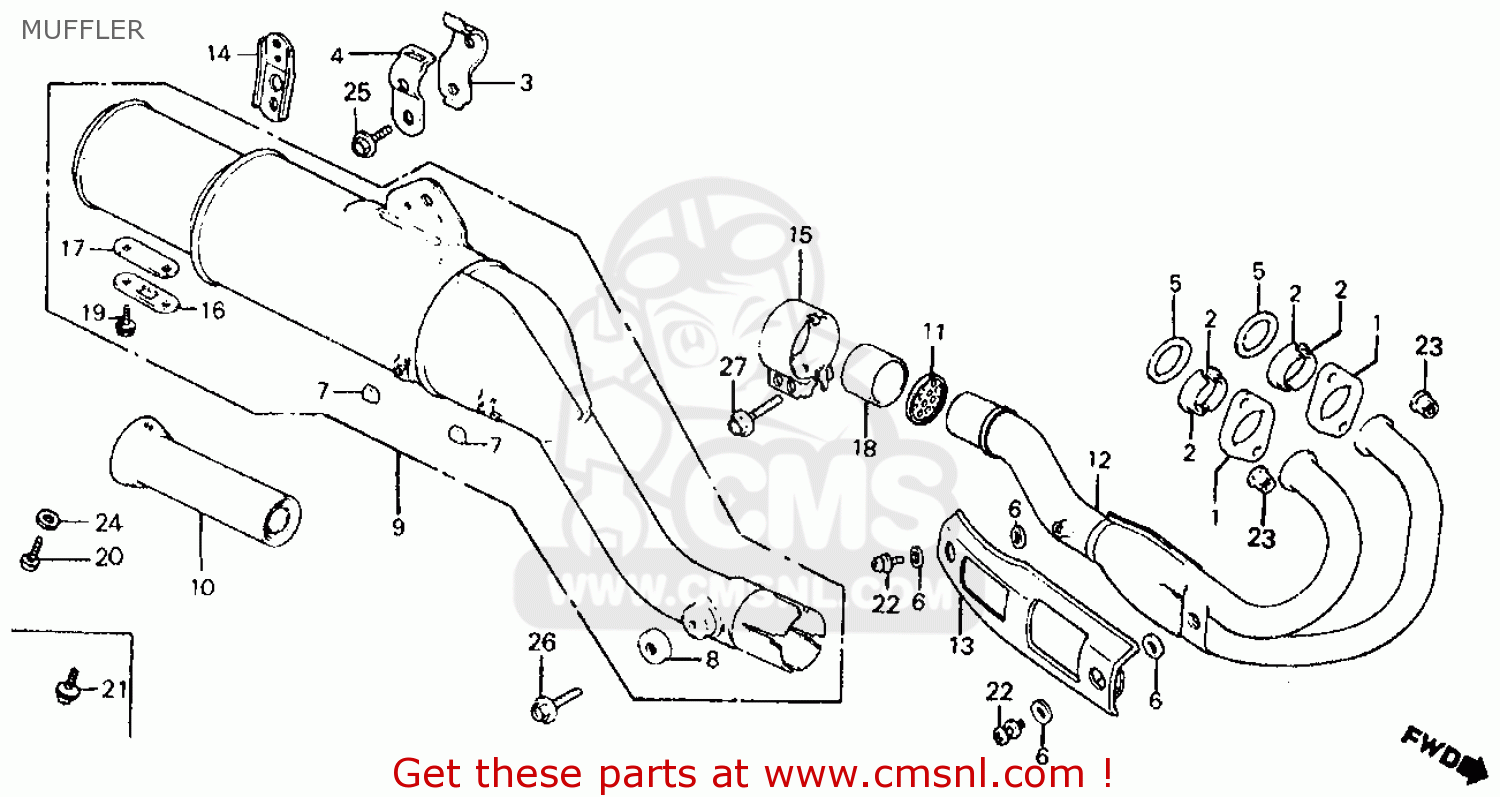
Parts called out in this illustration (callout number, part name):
1	JOINT,EX.PIPE
2	COLLAR,EX.PIPE
3	BAND A,MUFFLER
4	BAND B,MUFFLER
5	GASKET,EX PIPE (NAS)
6	PACKING,PROTECTOR (NAS)
7	RUBBER,PROTR.PKG. (NAS)
8	PACKING B,MUFFLER
9	MUFFLER COMP,EX.
10	PIPE COMP.,TAIL
12	PIPE COMP.,EX.
13	PROTECTOR,EX.PIPE
15	BAND,MUFFLER
16	LID,MUFFER
17	PKG,MUFFLER,LID (MCA)
18	PACKING,MUFFLER (MCA)
19	BOLT-WASH,6X12
21	SCREW-WASHER 6X12
22	SCREW-WASHER 6X12
25	BOLT,FLANGE,8X16
26	BOLT FLANGE 8X20
27	BOLT FRANGE 8X35
